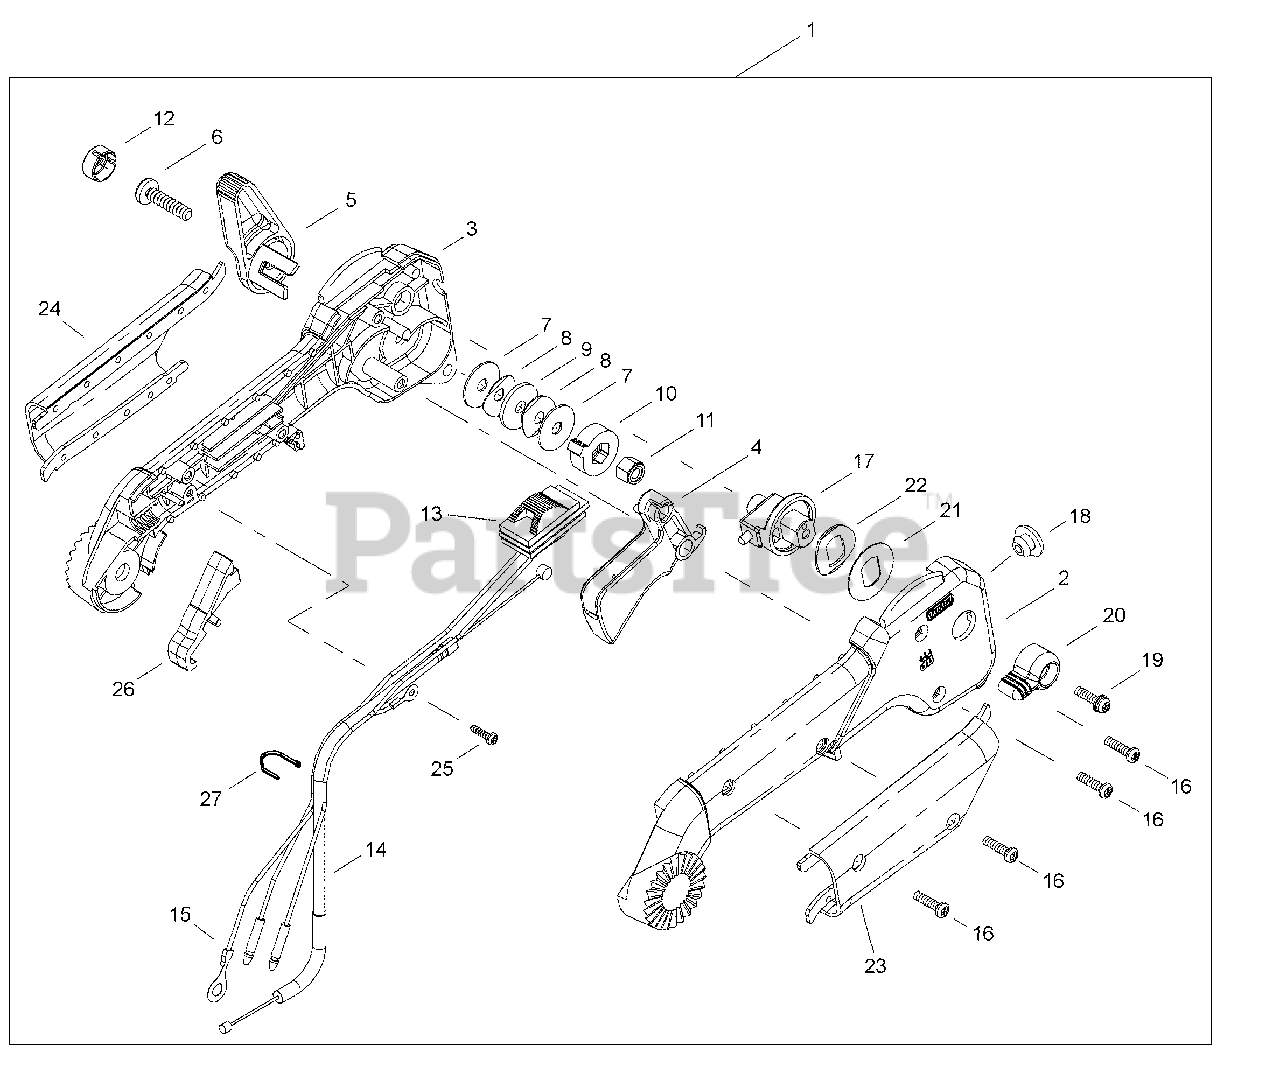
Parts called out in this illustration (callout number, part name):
1	HANDLE ASSY
2	HANDLE, CONTROL - RIGHT
3	HANDLE, CONTROL - LEFT
4	TRIGGER, THROTTLE
5	LEVER, LOCK
6	ADJUSTABLE BOLT
7	WASHER - 6
8	LOCKWASHER
9	WASHER - 6
10	PLATE
11	NUT - 6 -- NYLON
12	CRUISE CONTROL BOLT CAP
13	SWITCH, IGNITION
14	CABLE, THROTTLE
15	LEAD - GROUND
16	SCREW
17	ADJUSTER ASSY
18	PLUG
19	SCREW, METERING LEVER PIN
20	SCREW, METERING LEVER PIN
21	WASHER
22	WASHER - SPRING
23	GRIP - RIGHT
24	GRIP - LEFT
25	SCREW - 3
26	COVER, HANDLE
27	TIE, CABLE
